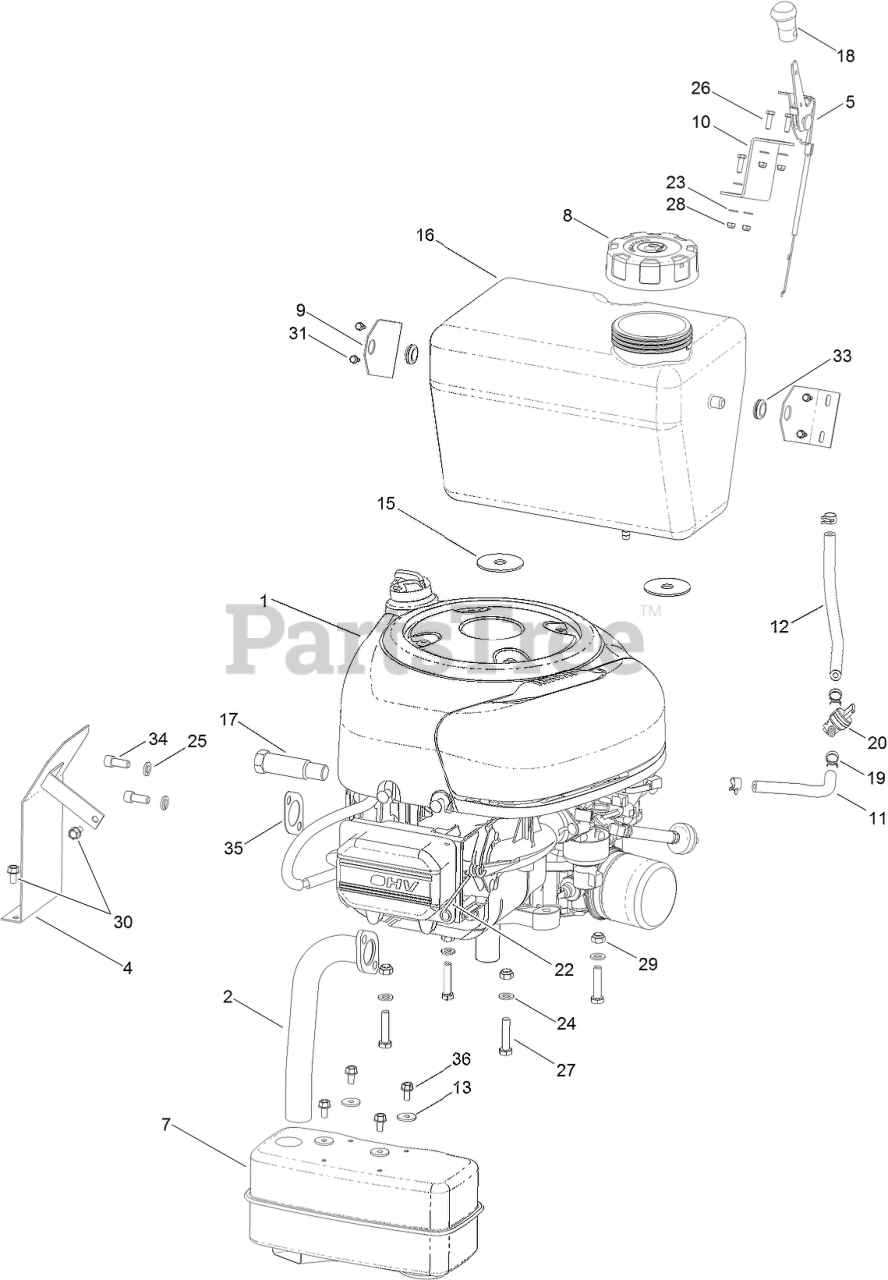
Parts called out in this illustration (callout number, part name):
2	TUBE-EXHAUST
4	COVER-EXHAUST
5	CABLE-THROTTLE/CHOKE
7	MUFFLER
8	CAP-FUEL
9	BRACKET-FUEL, TANK
10	HOLDER
11	LINE-FUEL
12	LINE-FUEL
13	WASHER-FLAT
15	WASHER-RUBBER
16	TANK-FUEL
17	COUPLER-DRAIN, OIL
18	KNOB-THROTTLE/CHOKE
19	CLAMP-LINE, FUEL
20	VALVE-TANK, FUEL
22	HOLDER-HARNESS, WIRING
23	WASHER
24	WASHER-PLAIN
25	WASHER-SPRING
27	SCREW-HH
28	NUT-LOCK
29	NUT-LOCK, NI
30	SCREW-HH
31	SCREW-TAP
33	BUSHING
34	SCREW-HH
35	GASKET
36	SCREW-HHTF
